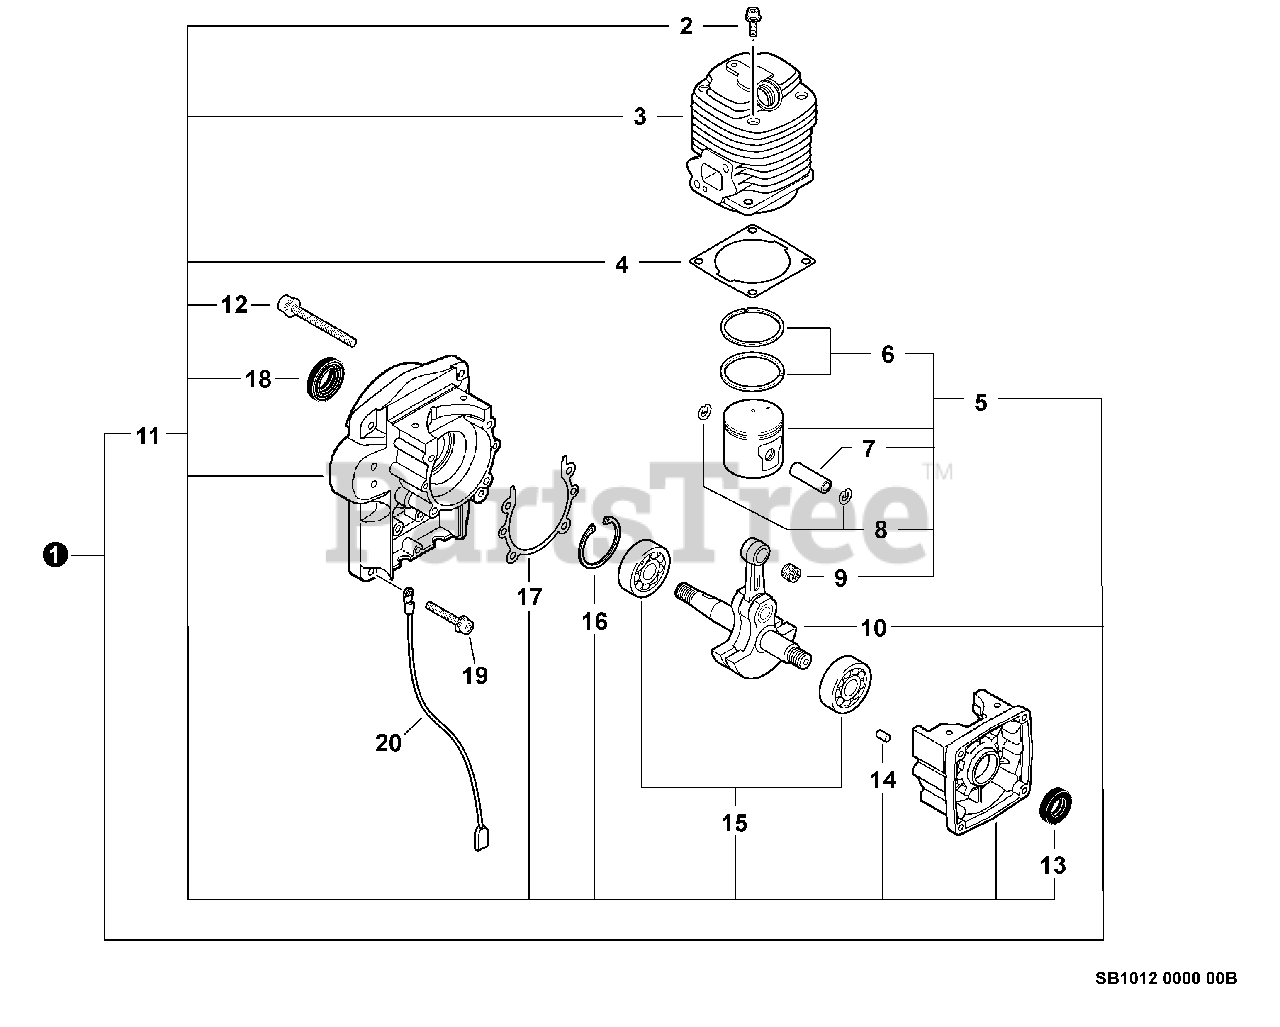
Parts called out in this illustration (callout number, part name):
1	SHORT BLOCK -- SB1012
2	SCREW - 5X22
3	CYLINDER
4	GASKET, CYLINDER
5	PISTON KIT
6	RING, PISTON
7	PIN, PISTON
8	RING, RETAINING - 8
9	BEARING, NEEDLE
10	CRANKSHAFT ASSY
11	CRANKCASE KIT
12	SCREW - 5X40
13	SEAL, OIL
14	PIN - LOCATING
15	BEARING, BALL - 6202
16	RING, RETAINING - 35
17	GASKET, CRANKCASE
18	SEAL, OIL
19	SCREW - 5X32
20	LEAD - GROUND
